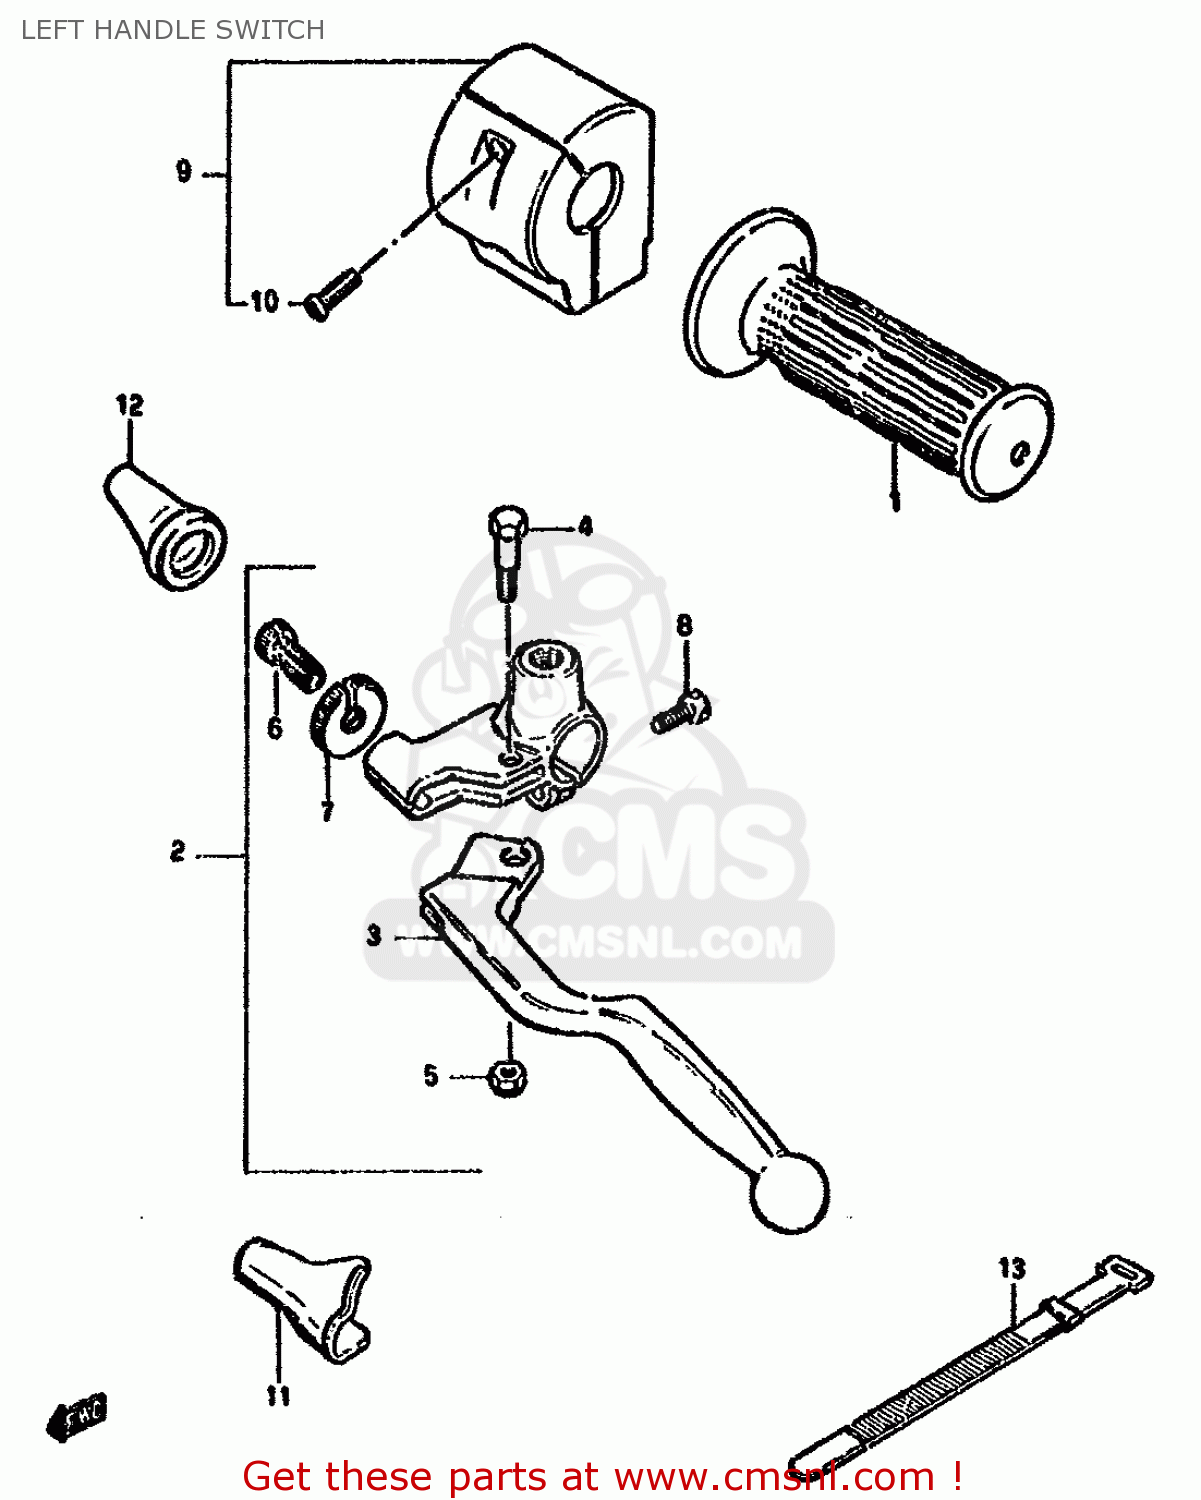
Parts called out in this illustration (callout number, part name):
1	GRIP,L
2	LEVER ASSY,CLUTCH
3	LEVER,CLUTCH
4	BOLT,LEVER PIVOT
5	NUT 6MM
6	ADJUSTER,CABLE
7	NUT,CABLE ADJUSTER
8	BOLT,CLUTCH LEVER HOLDER
9	SWITCH ASSY,HANDLE,L
10	SCREW
11	COVER,CLUTCH LEVER
12	BOOT,CLUTCH CABLE
13	CLAMP(L:120)
